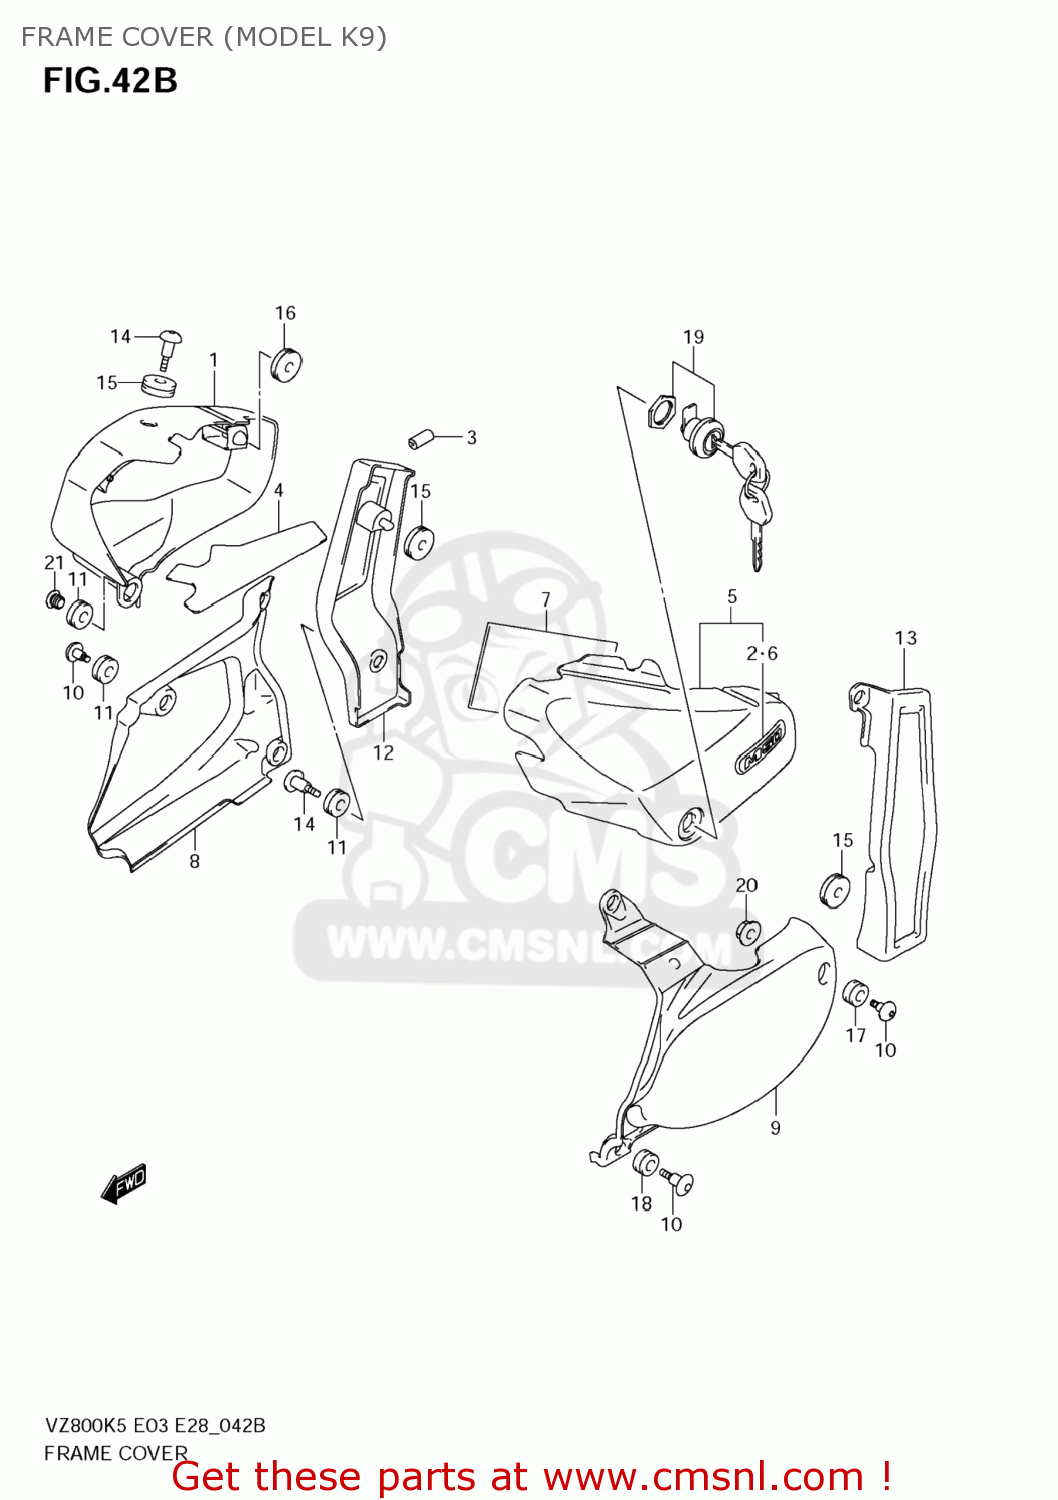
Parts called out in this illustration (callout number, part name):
1	COVER,SIDE,R(BLACK)
2	EMBLEM,M50
3	MOLDING
4	SHIELD,FRAME COVER
5	COVER,SIDE,L(BLACK)
6	EMBLEM,M50
7	CUSHION,LUGGAGE BOX
8	COVER,SIDE LWR,R
9	COVER,SIDE LWR,L
10	SCREW,SIDE COVER LWR,R
11	CUSHION
12	COVER,SIDE RR,R
13	COVER,SIDE RR,L
14	SCREW(6X20)
15	CUSHION
16	CUSHION
17	CUSHION
18	CUSHION
19	LOCK SET,COVER
20	NUT
21	CAP(OD:14)
